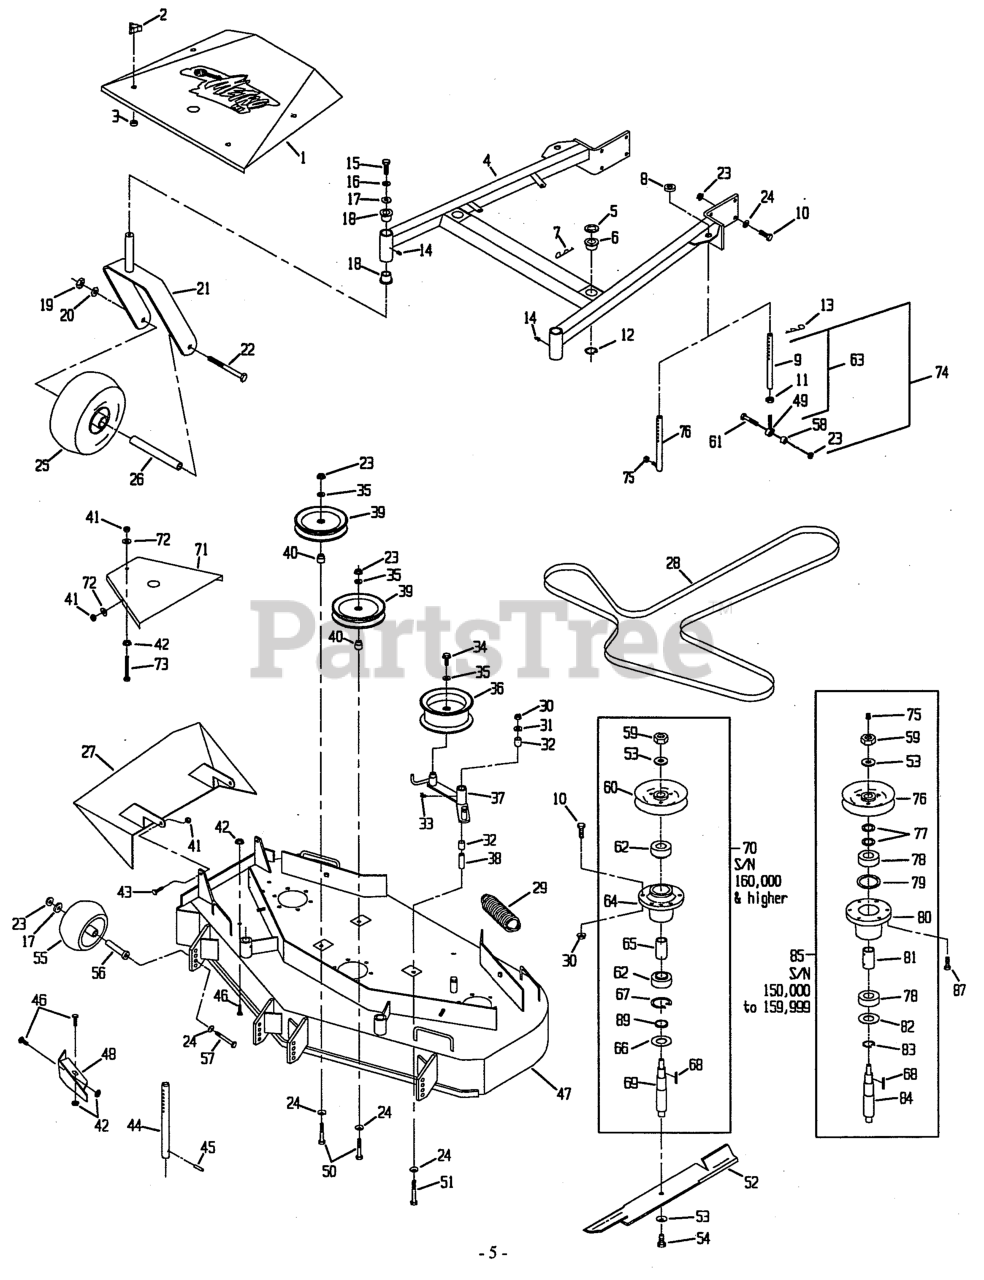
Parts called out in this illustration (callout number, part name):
1	Shield, Belt W/Decals
2	Washer, Belt Cover
3	Washer, Belt Cover
4	Support Weldmt W/Bushings &Decals
5	Spacer, Front Deck Support
6	Bushing, Deck Support
7	Hairpin, Cotter
8	Spacer, Blade Drive
9	Link, Deck Support
10	Screw, Hex Cap 3/8-16x1-1/4
11	Nut, Reg Hex 3/8-24
12	Ring, Retaining
13	Hairpin, Cotter
14	Zerk, Straight 1/8
15	Screw, Hex Cap 3/8-16x1
16	Washer, 3/8 Heavy Spring
17	Washer, Swivel
18	Bearing, Flange
19	Nut, Reg Hex 1/2-13
20	Washer, Lock Hlcl Spg 1/2 Reg
21	Caster Weldmt
22	Screw, Hex Cap 1/2-13x6
23	Nut, Whizlock 3/8-16
24	Washer, Disc Spring 3/8
25	Tire & Wheel Assembly
26	Spacer
27	Chute Weldmt, Discharge
28	Belt, Deck Drive
29	Spring, Extension
30	Nut, Nyloc 3/8-16
31	Washer, Flat Std 3/8
32	Pivot, Bearing
33	Zerk, 90 Degree 1/4-28
34	Bolt, Whizlock 3/8-16x1
35	Washer, Flat 3/8 SAE
36	Pulley, Idler
37	Arm, Weldmt
38	Bushing, Idler Pivot
39	Pulley, Idler
40	Bushing, Idler
41	Nut, Nylock 5/16-18
42	Nut, Whizlock 5/16-18
43	Screw, Hex Cap 5/16-18x1
44	Rod, Deck Support
45	Rollpin, 1/4x1-1/2
46	Screw, Hex Cap 5/16-18x5/8
47	Deck Weldmt W/Decals, Discharge Baffle & Support Rods
48	SPACER-WHEEL
49	Ball Joint
50	Screw, Hex Cap 3/8-16x2-3/4
51	Screw, Hex Cap G8 3/8-16x3-1/2
52	Blade, 1625
53	Washer, Spring Disc
54	Screw, Hex Cap 5/8-11x1
55	Roller, Antiscalp
56	Bushing, Roller
57	Screw, Hex Cap G8 3/8-16x4
58	Bushing Spacer
59	Nut, Reg Hex 5/8-18
60	Sheave W/Hub
61	Screw, Hex Cap 3/8-16x1-3/4
62	Bearing
63	Link, Assembly
64	Housing, Spindle
65	Spacer, Bearing
66	Gaurd, Bearing-Bottom
67	Ring, Snap
68	Key, Machine
69	Shaft, Spindle
70	Housing, Cutter Assembly
71	Shield, Belt
72	Washer, Flat Std 5/16
73	Bolt, Hex Tap 5/16-18x3 1/4
74	Kit, Link Assembly
75	Nut, Torque 3/8-24
77	Sheave W/Hub
78	Washer, .060
79	Bearing, Spindle
80	O-Ring, Cutter Housing
81	Housing, Bearing
82	Spacer, Bearing
83	Seal, Mech Dust
84	Ring, Snap
85	Shaft, Spindle
87	Screw, Hex Taptite 3/8x16x1
88	Zerk, Straight 1/4-28
89	Spacer
